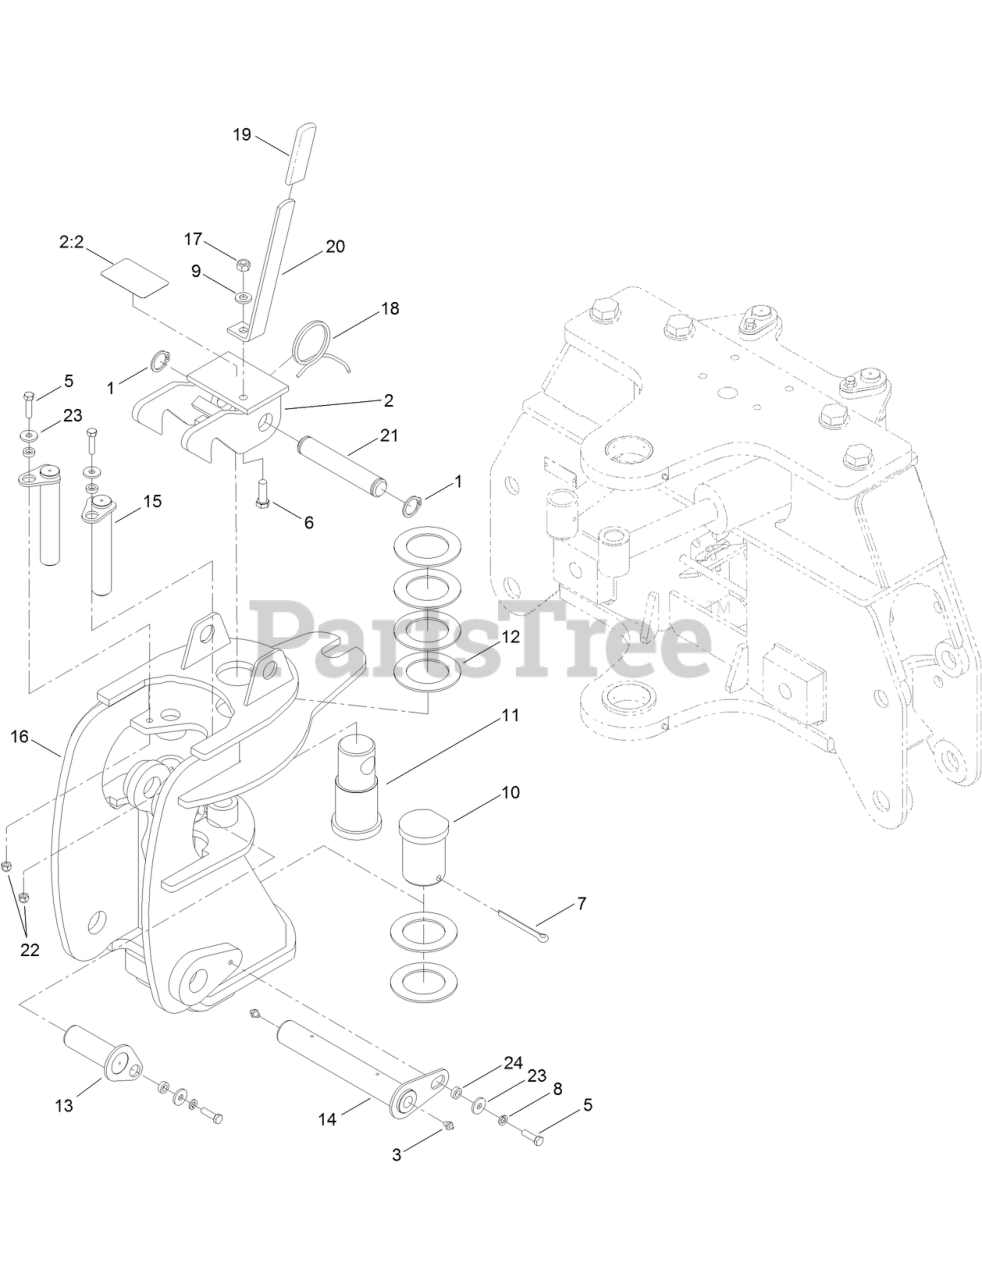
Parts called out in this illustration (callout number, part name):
1	RING-RETAINING, EXTERNAL
2	BOOM LOCK LATCH ASM
2:2	DECAL-OPERATOR PRESENCE
3	FITTING-GREASE
5	SCREW-HH
6	SCREW-HH
7	PIN-COTTER
8	WASHER-LOCK
9	WASHER-FLAT
10	PIN-PIVOT, LOWER
11	PIN-PIVOT, UPPER
12	WASHER-THRUST PIVOT
13	PIN-Boom Cylinder
14	PIN-BOOM PIVOT
15	PIN-PIVOT W/FLAG
16	FRAME-PIVOT
17	LOCKNUT
18	SPRING-Torsion
19	GRIP-HANDLE
21	PIN-PIVOT
22	NUT-HEX
23	WASHER-HARDENED
